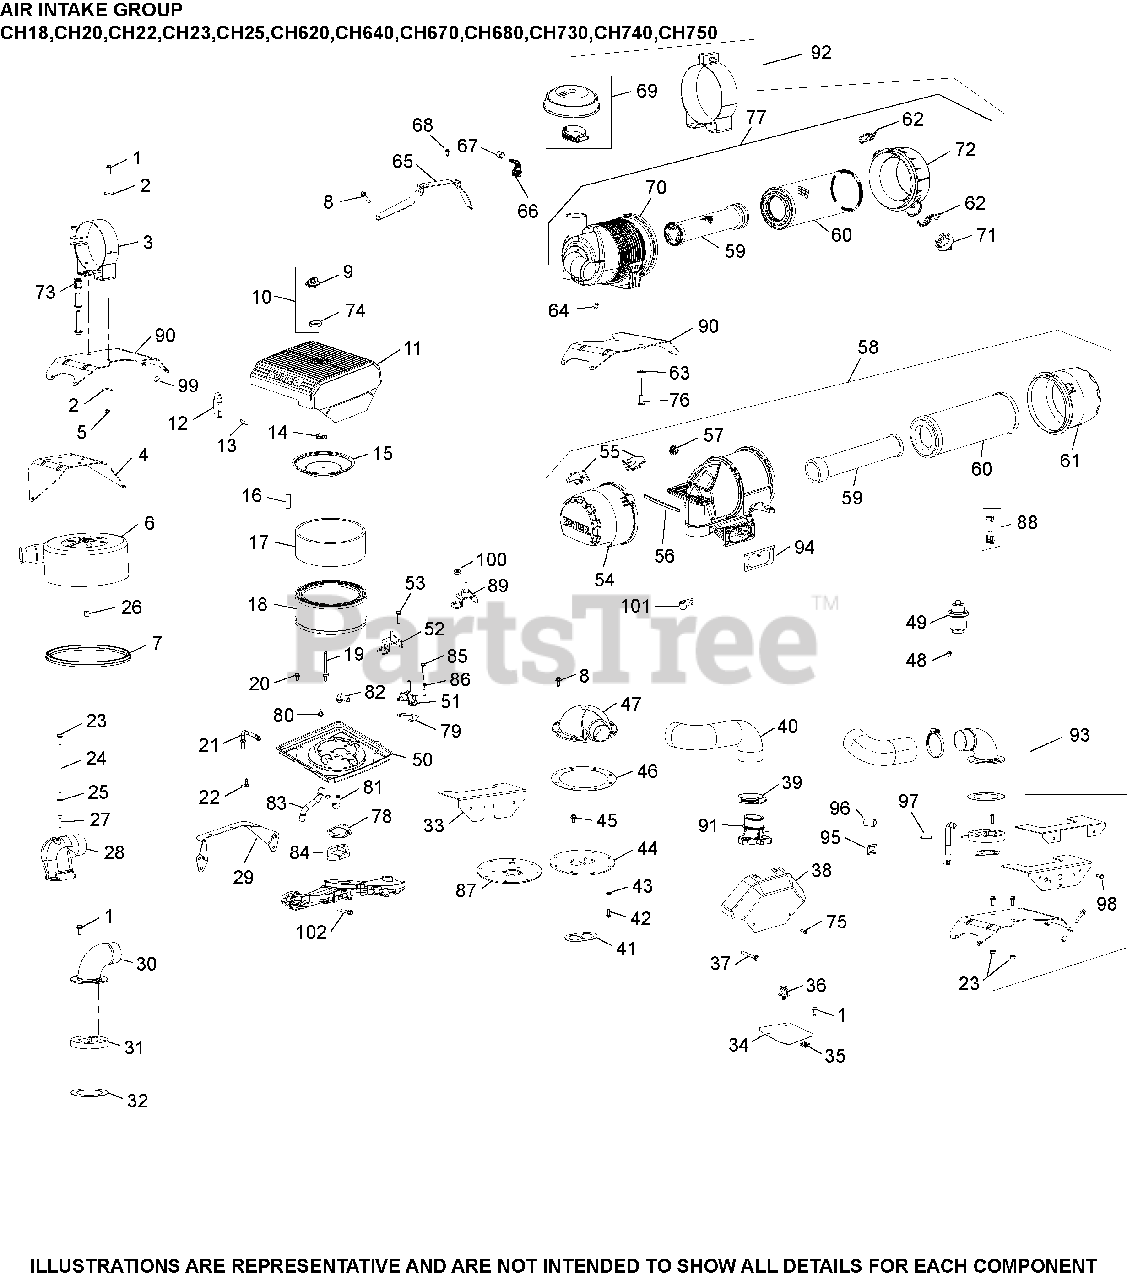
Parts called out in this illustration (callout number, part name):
1	SCREW, FLG M6X1.0X16
3	BRACKET, AIR CLEANER
5	NUT, LOCK M6X1.0
33	SHIELD, DEBRIS
37	SCREW, FLG M6X1.0X55
39	CLAMP, HOSE
40	HOSE, AIR CLEANER
53	SCREW, FLG M6X1.0X25
59	ELEMENT, AIR FILTER - SAFETY
60	ELEMENT, AIR FILTER - PRIMARY
62	LATCH ASSEMBLY
64	PLUG, PIPE
69	HOOD, INLET
71	VALVE, ACUATOR
72	COVER ASSEMBLY
73	SPRING, AIR CLEANER BRACKET
77	AIR CLEANER (W/DIRTY-SIDE EVAP FITTING)
78	GASKET, AIR CLEANER BASE
88	KIT, ADAPTER TUBE
90	BRACKET, AIR CLEANER
91	KIT, REMOTE AIR CLEANER ADAPTER
97	CAP, MASKING
98	SCREW, HI-LOW
